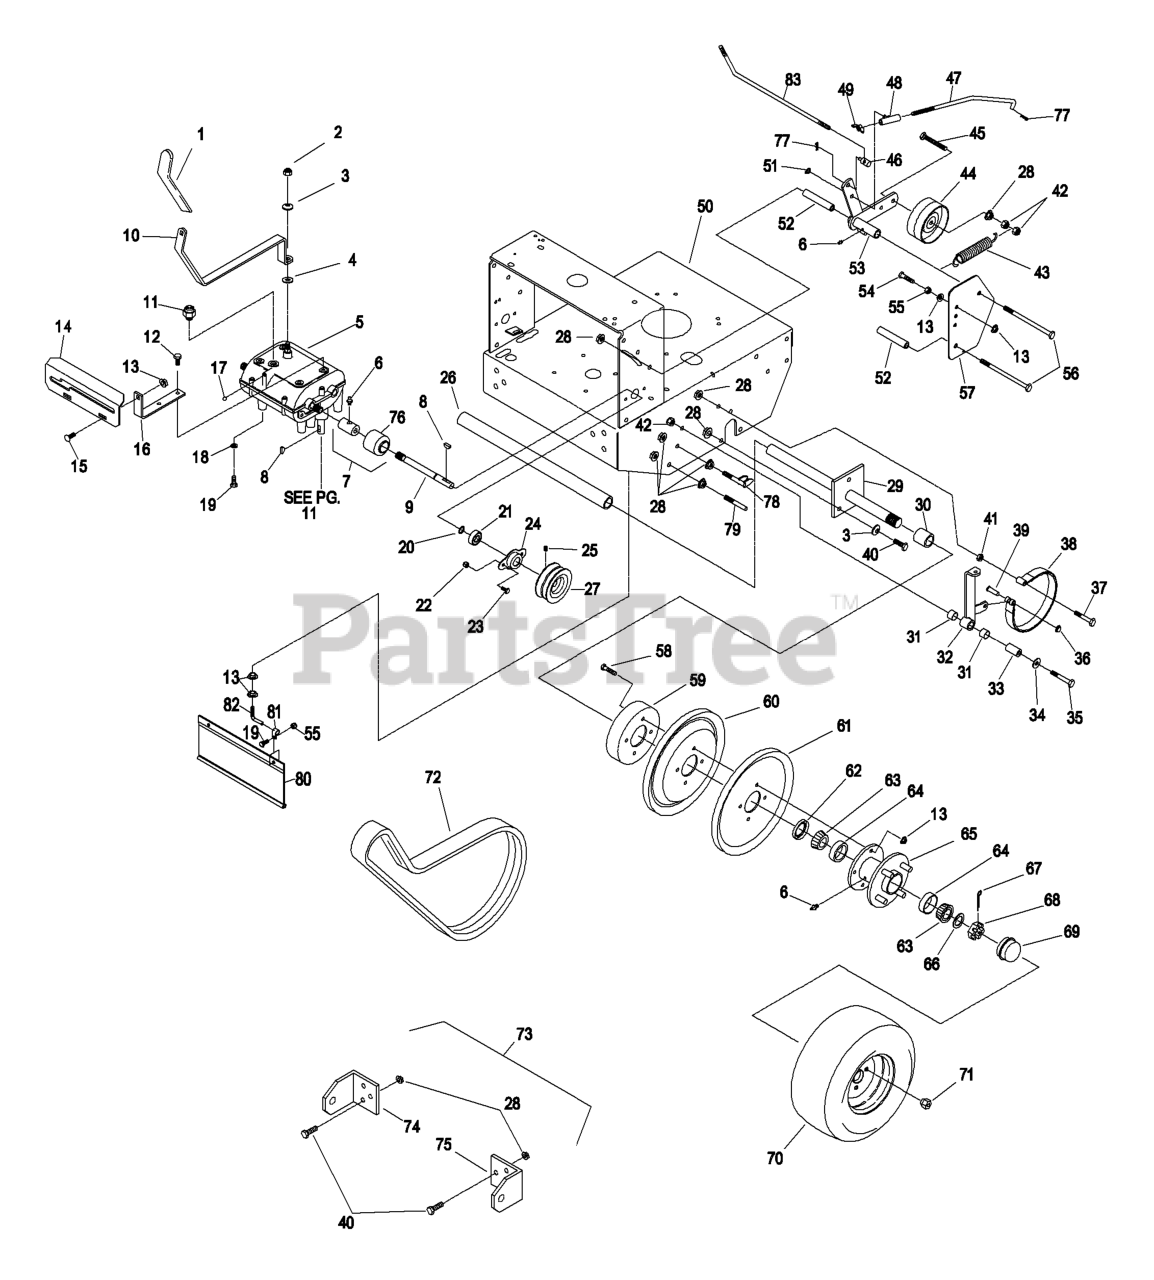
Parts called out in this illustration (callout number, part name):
1	GRIP,FOAM
2	NUT-LOCK
3	WASHER-BELLEVILLE
6	FITTING-GREASE
7	ASM,COUPLER/ZERK
8	KEY-WOODRUFF
9	SHAFT-TRANSMISSION
10	ASM,SHIFT LEVER
11	SWITCH-START, NEUTRAL
12	SCREW-HWH, THREAD CUT
15	BOLT-CARR
16	BRACKET-PLATE, SHIFT
17	BALL,DETENT (SERVICE ONL
18	WASHER-LOCK
19	SCREW-HH
20	RING-RETAINING
21	BEARING-SHAFT
22	NUT-LOCK, NI
23	SCREW-HH
24	FLANGE-OUTPUT
25	SCREW-SET
26	SLEEVE,AXLE
28	NUT-HHF, WHIZ
30	SPACER,WHEEL SHORT
31	SLEEVE-BUSHING
32	ASM,RH BRAKE LEVER W/BSHG
33	BUSHING-PIVOT
34	WASHER-FLAT
35	SCREW-HH
36	RING-RETAIN,PUSH,EXT,FLAT
37	SCREW-HH
38	BAND-BRAKE
39	PIN-CLEVIS
40	SCREW-HH
41	NUT-JAM
42	NUT-LOCK, NI
43	SPRING-EXTENSION
44	IDLER-WHEEL, DRIVE
45	SCREW-HH
46	SWIVEL-DRIVE LEVER, 3/8 L
49	WINGNUT-NYLOCK
51	RING-RETAINING
52	SPACER-SHIELD
53	WLD,RH IDLER ARM
54	SCREW-HH
55	NUT-LOCK, NI
56	SCREW-HH
57	SHIELD,WHEEL DRIVE
58	SCREW-HH
59	DRUM-BRAKE
60	SHEAVE,WHEEL DRIVE
61	SHEAVE,WHEEL DRIVE
62	SEAL-GREASE
63	Cone-Bearing Tapered Roller
64	CUP-BEARING
65	HUB/WHEEL ASM
66	WASHER-SPACER
67	PIN-COTTER
68	NUT-SHH
69	CAP-GREASE
70	WHEEL AND TIRE ASM
71	NUT-LUG
72	BELT,WHEEL DRIVE BANDED
73	Kit, Sulky Hitch
76	GUARD-COUPLER
77	PIN-COTTER
78	SCRAPER
80	SHIELD-TRAILING
81	CLIP-LOOM
82	MOUNT,DRAG SHIELD
83	LINKAGE,DRIVE (PLT)
